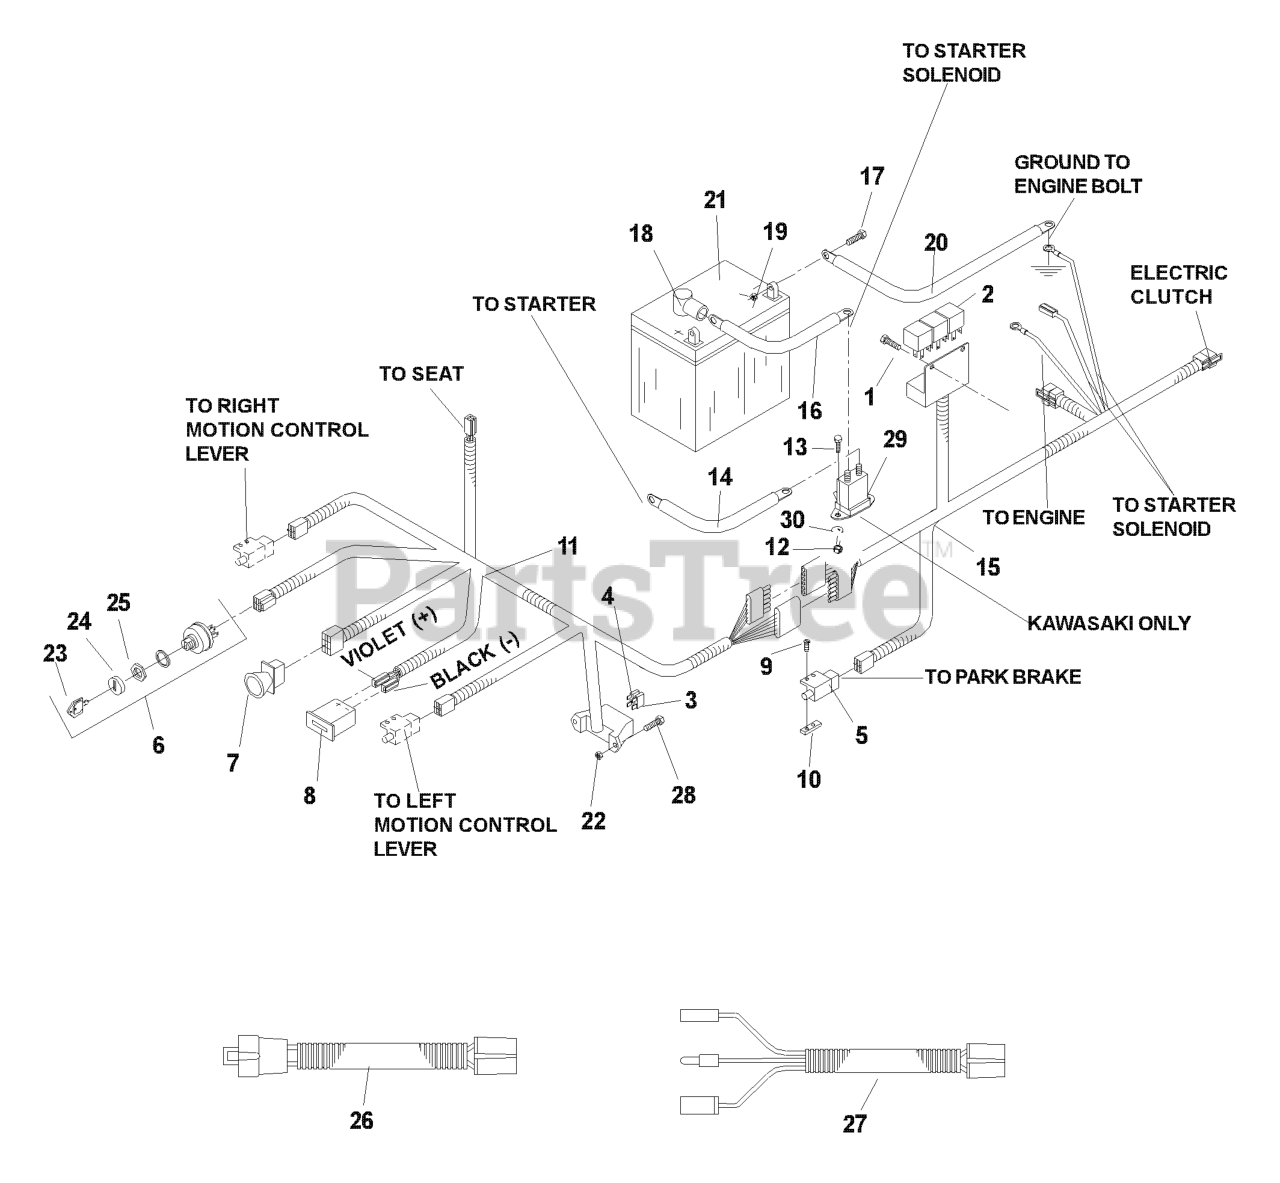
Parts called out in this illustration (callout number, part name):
1	SCREW #10 X 1/2 SELF TAPPING
3	FUSE, 7.5 AMP 32 VOLT ATO
4	FUSE, 20 AMP 32 VOLT ATO
5	SWITCH, INTERLOCK
6	IGNITION SWITCH KIT
7	RP.SWITCH, BLADE
8	DIGITAL HOUR METER
9	SCREW #10-24 X 5/8
10	TAPPED PLATE
11	CONSOLE HARNESS
12	NUT 1/4C CENTERLOCK
13	HCS 1/4C X 5/8
14	POST.CABLE LONG
14	CABLE POSITIVE
15	FRAMES HARNESS
16	CABLE POSITIVE, LONG
17	HCS 5/16C X 3/4
19	NUT 5/16C CENTERLOCK
20	CABLE-NEGATIVE
21	BATTERY WET NOT SELLABLE
22	NUT 10-24 NYLOC
23	KEY-PADDED
24	CAP IGNITION NUT
25	DNO IGNITION NUT
26	KOH PIGTAIL
27	KAW PIGTAIL
28	SCREW, #1--24 X 1/2 SLOTTED
29	SOLENOID
30	WASHER 1/4 INT TOOTH
